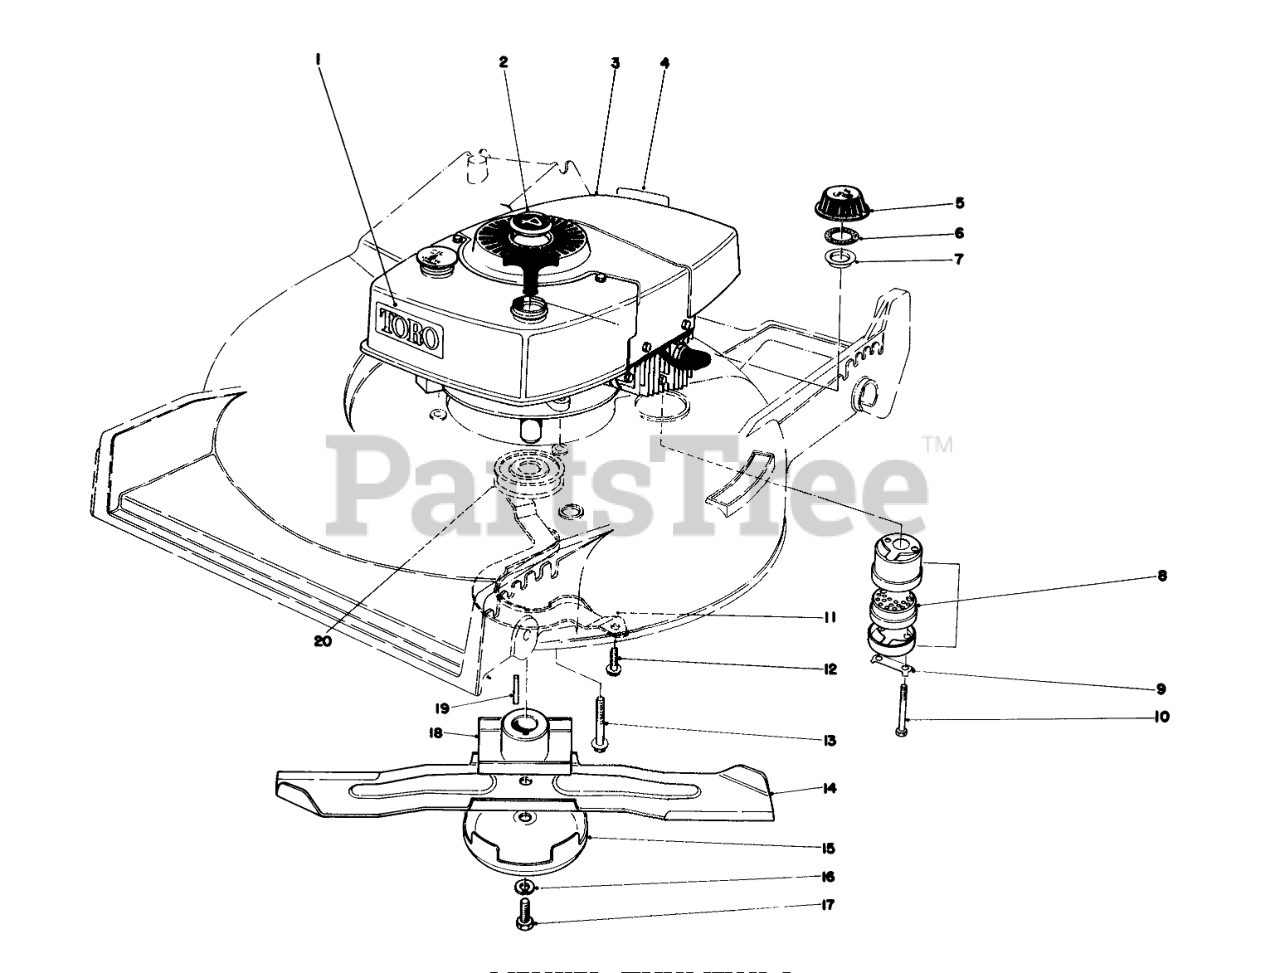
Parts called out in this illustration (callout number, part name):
1	Decal Toro
2	Plug Button
3	Engine
4	Decal-Maintenance
5	Gas Cap (Incl. Ref. #6 & 7)
6	GASKET
7	GAS CAP BAFFLE
8	Muffler Assy. (Incl. Ref. #9 & 10)
9	CLIP - LOCKING
10	SCREW-HH
11	BELT GUIDE
12	Screw
13	SCREW-HWHTF
14	Blade
15	Anti Scalp Cup
16	WASHER-LOCK
17	BLADE SCREW
18	BLADE RETAINER WA(BLACK)
19	KEY-SQUARE
20	Pulley
